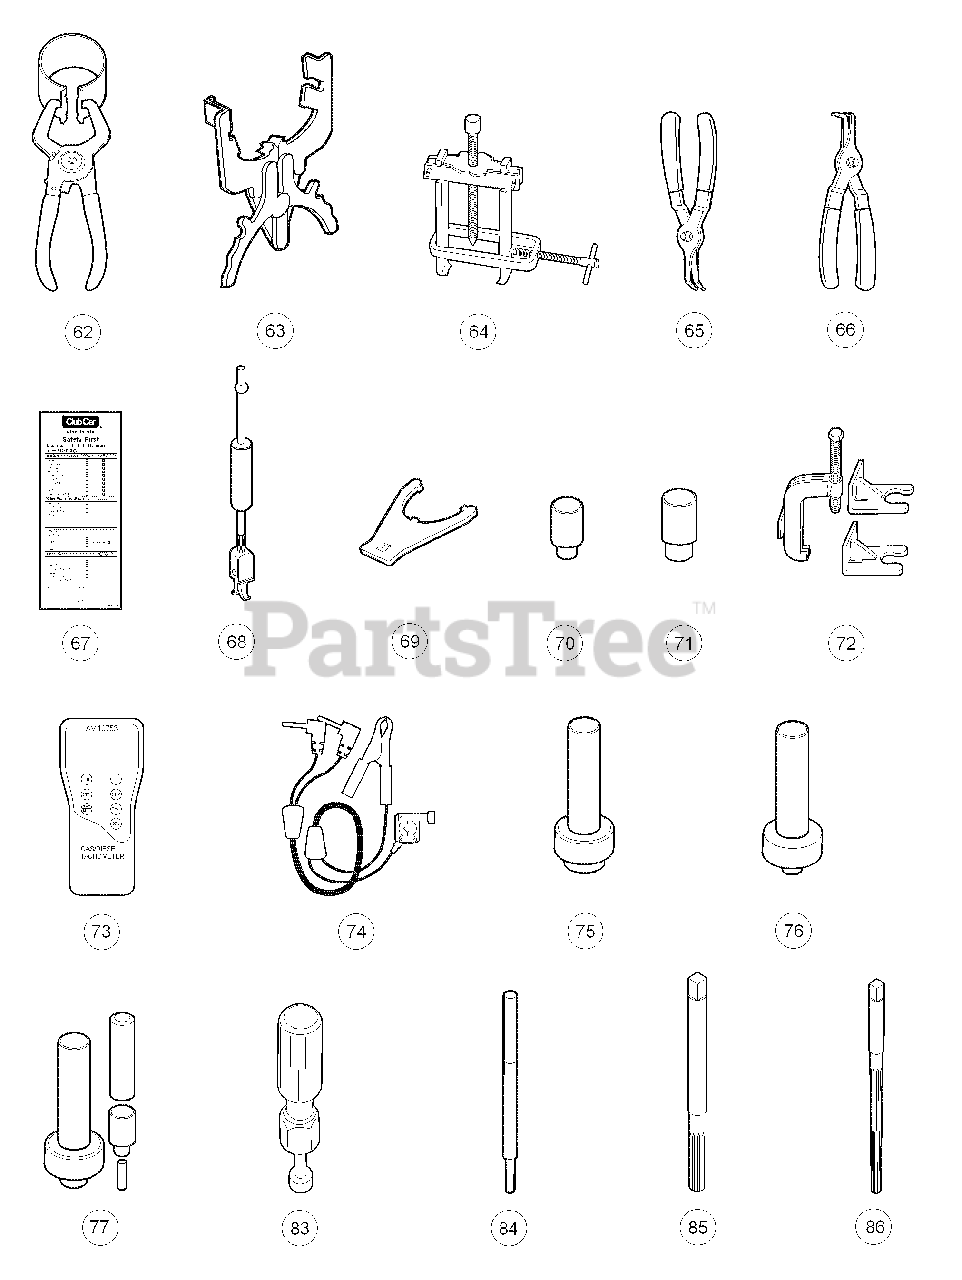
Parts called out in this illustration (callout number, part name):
62	Piston Ring Compressor Kit
63	Piston Ring Pliers
64	Puller, Special Use
65	Retaining Ring Pliers, 45° External
66	Retaining Ring Pliers, 90° Internal
67	Safety First Card
68	Seal Puller
69	Spanner Wrench
70	Steering Column Bearing Press Tool
71	Steering Column Retaining Ring Tool
72	Steering Wheel Puller Tool
73	Tachometer
74	Tachometer Diesel Probe
75	Transaxle Axle Seal Tool
76	Transaxle Pinion Seal Tool
77	Transmission Tool Kit
82	Valve Clearance Adjuster Screw Holder
83	Valve Guide Driver
84	Valve Guide Reamer
85	Valve Guide Reamer, 6.6 mm
